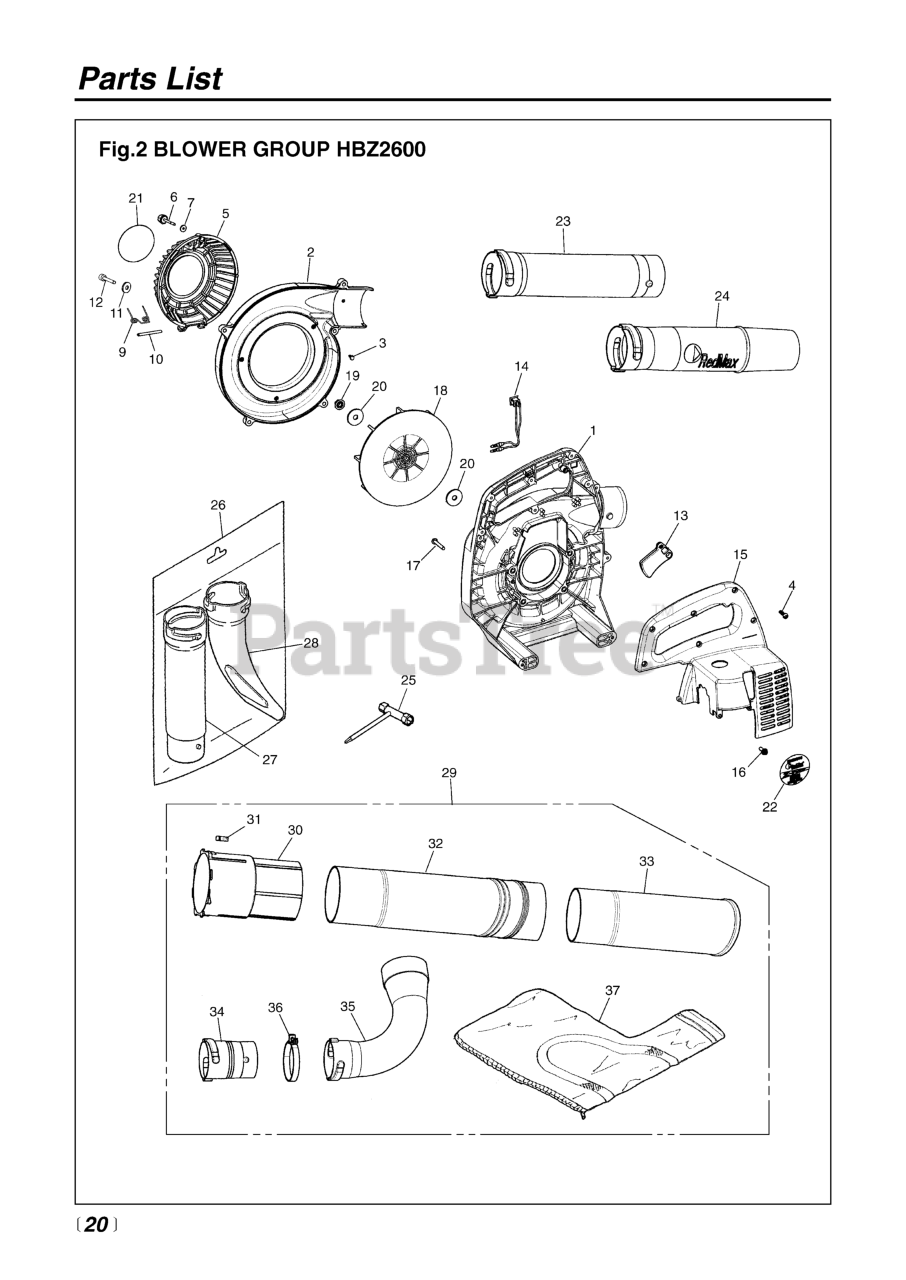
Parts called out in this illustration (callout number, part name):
1	VOLUTE CASE (RPLS. 6811-11110)
2	VOLUTE COVER (HBZ2600)
3	SCREW
5	GUARD NET
6	SCREW
7	WASHER
9	SPRING
10	SHAFT
13	LEVER
14	SWITCH
15	ENGINE COVER
16	BOLT
17	SCREW
18	FAN
20	WASHER
21	LABEL, CAUTION
22	LABEL, RECOIL
23	PIPE, STRAIGHT
24	PIPE, END
26	FLAT NOZZLE SET
28	NOZZLE, FLAT
29	VACUUM KIT
30	PIPE, A
32	PIPE, B
33	PIPE, C
34	EXTENSION (PIPE)
35	ELBOW
36	CLAMP
37	BAG, DUST
